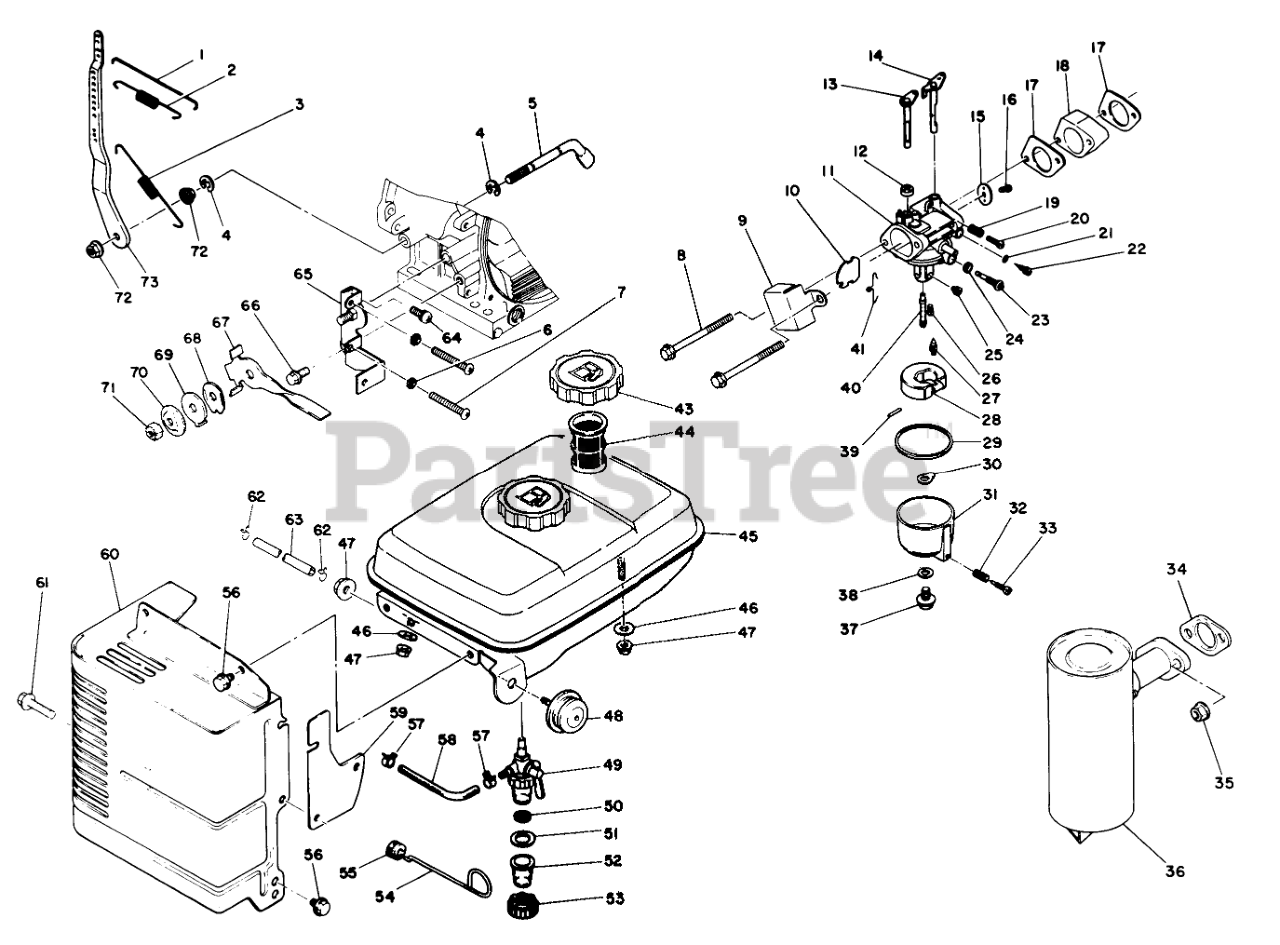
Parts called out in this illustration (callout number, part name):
1	GOV.ROD
2	SPRING-ROD
3	SPRING
4	SNAP RING
5	GOV SHAFT
7	SCREW
9	COVER
10	CHOKE VALVE
11	Carburetor Assembly (Incl. Ref. #10-16, 19-33 & 37-41)
13	SHAFT
14	THROTTLE SHAFT
15	THROTTLE VALVE
16	SCREW
17	CARB GASKET
18	INSULATOR
19	SPRING
20	SCREW
21	O - RING
22	Valve-Needle (Incl. Ref. #21)
23	SLOW JET
24	GASKET
25	MAIN JET
26	SCREW
27	VALVE
28	FLOAT
29	GASKET
30	GASKET
31	Bowl-Float (Incl. Ref. #32 & 33)
32	SPRING
33	SCREW
34	GASKET
36	MUFFLER
38	GASKET
39	FLOAT PIN
40	MAIN NOZZLE
43	FUEL TANK CAP
44	FUEL FILTER
45	Fuel Tank Assembly (Incl. Ref. #43, 44 & 46)
46	GASKET
49	Petcock-Fuel (Incl. Ref. #50-53)
50	SCREEN
51	GASKET
55	GROMMET
59	COVER
60	COVER
62	CLAMP
64	SCREW W/WASHER
65	BRACKET
67	LEVER
68	LEAF SPRING
69	WASHER
70	WASHER
73	GOV.LEVER
